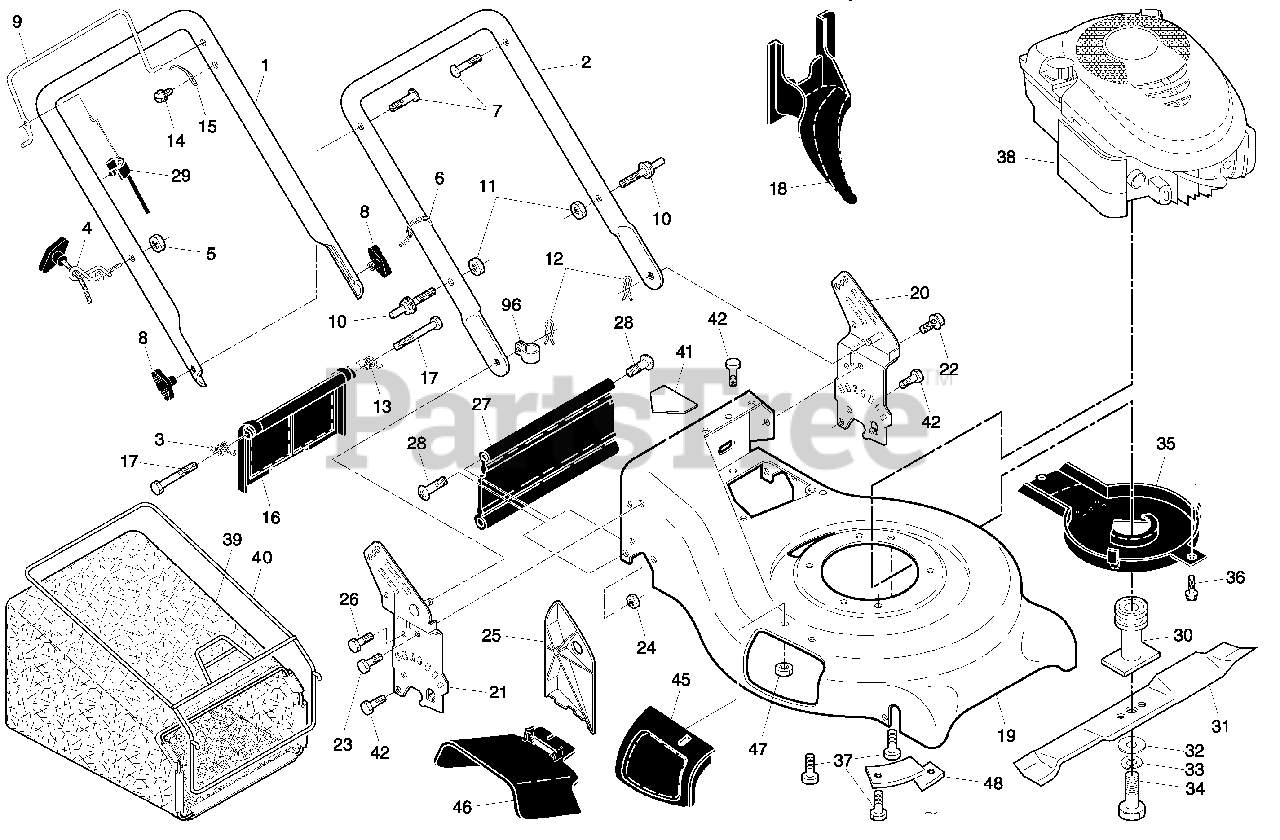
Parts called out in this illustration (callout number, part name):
1	Handle, Upper
2	Handle, Lower
3	Spring, Rear Door, RH
4	Rope Guide
5	Nut, Hex, with Lockwasher Insert 1/4-20
6	Wire, Tie
7	Bolt, Handle 5/16-18 x 2-5/8
8	Knob, Handle
9	Control Bar
10	Pin, Handle
11	Nut, Hex
12	Cotter, Hairpin
13	Spring, Rear Door, LH
14	Screw
15	Bracket, Upstop
16	Rear Door Assembly
17	Bolt, Rear Door
18	Plug, Mulcher
19	Kit, Housing
20	Handle Bracket Asembly, LH
21	Handle Bracket Assembly, RH
22	Screw, Hex Washer Head
23	Bolt, Hex Head 5/16-18 x 5/8
24	Nut, Hex, with Lockwasher Insert 5/16-18
25	Baffle, Side
26	Screw, Hi-Lo Thread #12 x 5/8
27	Skirt, Rear
28	Screw, Hinge 1/4-20 x 1.25
29	Cable, Operator Presence
30	Blade Adapter / Pulley
31	Blade, 21"
32	Washer
33	Washer, Lock
34	Bolt, Hex Head
35	Debris Shield
36	Bolt
37	Bolt, Engine
39	Grassbag
40	Frame, Grassbag
41	Danger Decal
42	Screw
45	Mulcher Door Assembly
46	Discharge Guard
47	Nut, Hex
48	Mounting Bracket, Debris Shield
96	Clip, Cable
96	Operator's Manual, English
96	Operator's Manual, French
96	Repair Parts Manual, English/French
